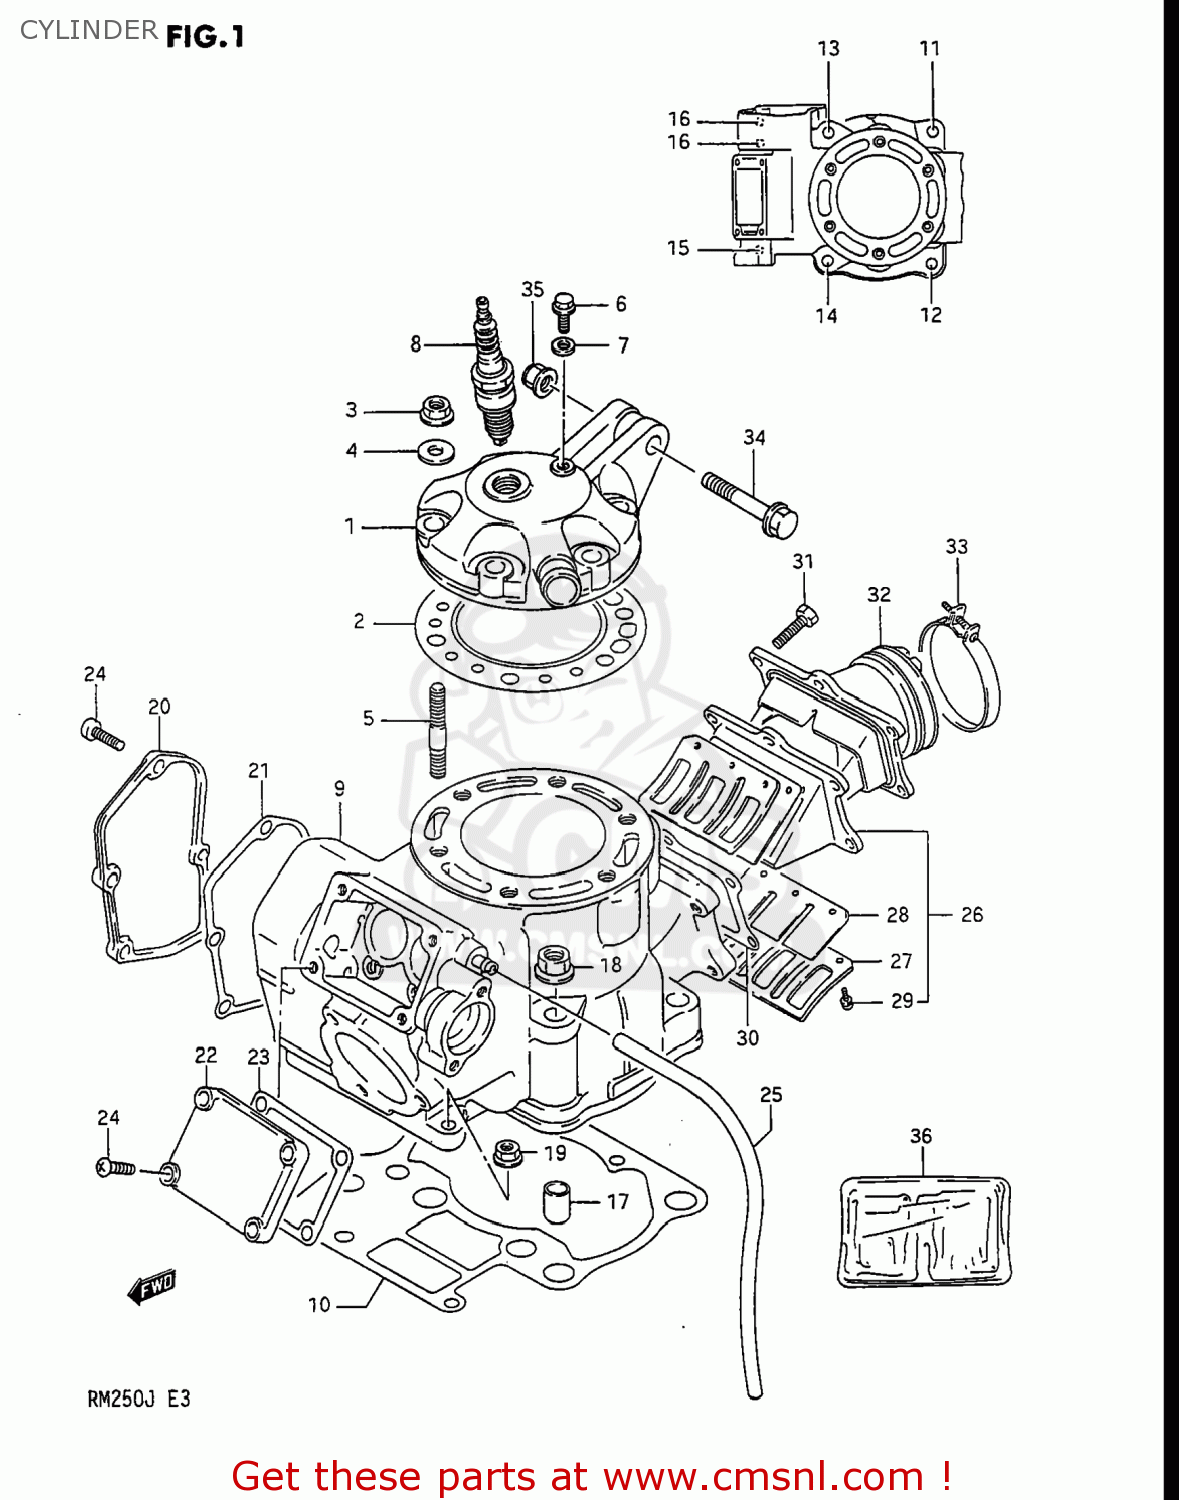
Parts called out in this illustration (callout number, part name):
1	HEAD,CYLINDER
2	GASKET,CYLINDER HEAD
3	NUT
4	WASHER
5	BOLT,STUD
6	UNION
7	GASKET(6.2X11X1).2 (NAS)
8	PLUG,SPARK(NGK B-8EN)
9	CYLINDER
10	GASKET,CYLINDER (MCA)
11	STUD BOLT (L:40)
12	STUD BOLT (10X50)
13	STUD
14	STUD BOLT (10X90)
15	STUD 6X25
16	STUD BOLT
17	PIN
18	NUT
19	NUT
20	COVER,CYLINDER NO.1
21	GASKET,CYLINDER COVER (MCA)
22	COVER,CYLINDER NO.2
23	GASKET,CYLINDER COVER NO.2 (MCA)
24	SCREW
25	HOSE
26	VALVE ASSEMBLY,REED
27	STOPPER,REED VALVE
28	VALVE,REED
29	SCREW,REED VALVE
30	GASKET,REED VALVE (MCA)
31	BOLT
32	PIPE,INTAKE
33	CLAMP
34	BOLT 8X45
35	NUT
36	GASKET SET (MCA)
